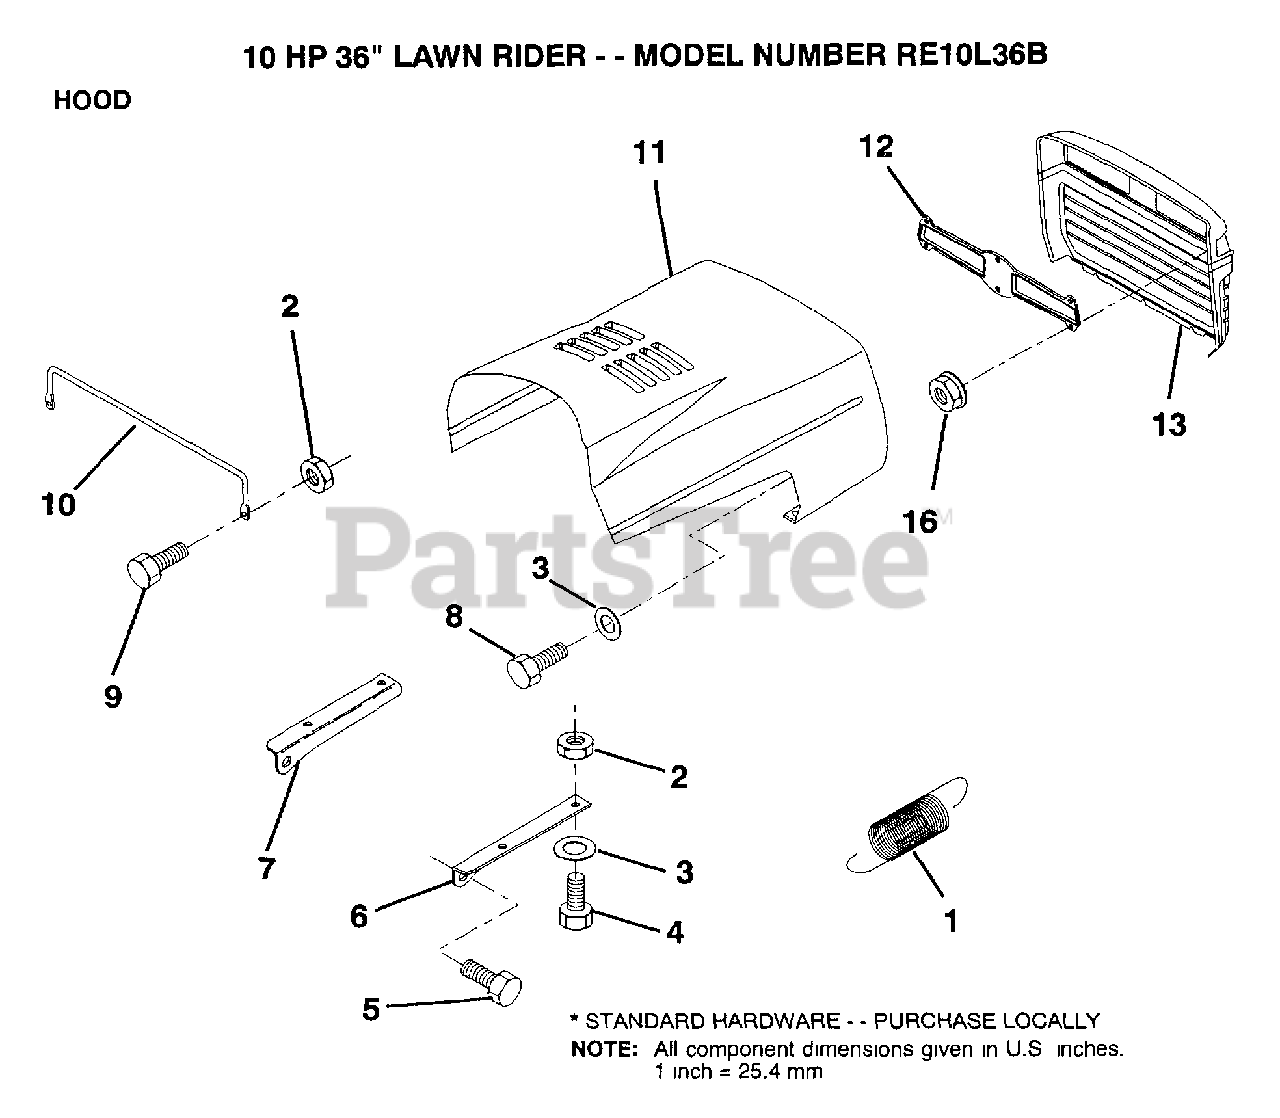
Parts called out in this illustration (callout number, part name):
1	EXT SPRING
2	NUT
3	WASHER
4	BOLT
6	BRKT HOOD RH
7	BRKT HOOD LH
10	"BRACE,HOOD"
11	HOOD
16	NUT
